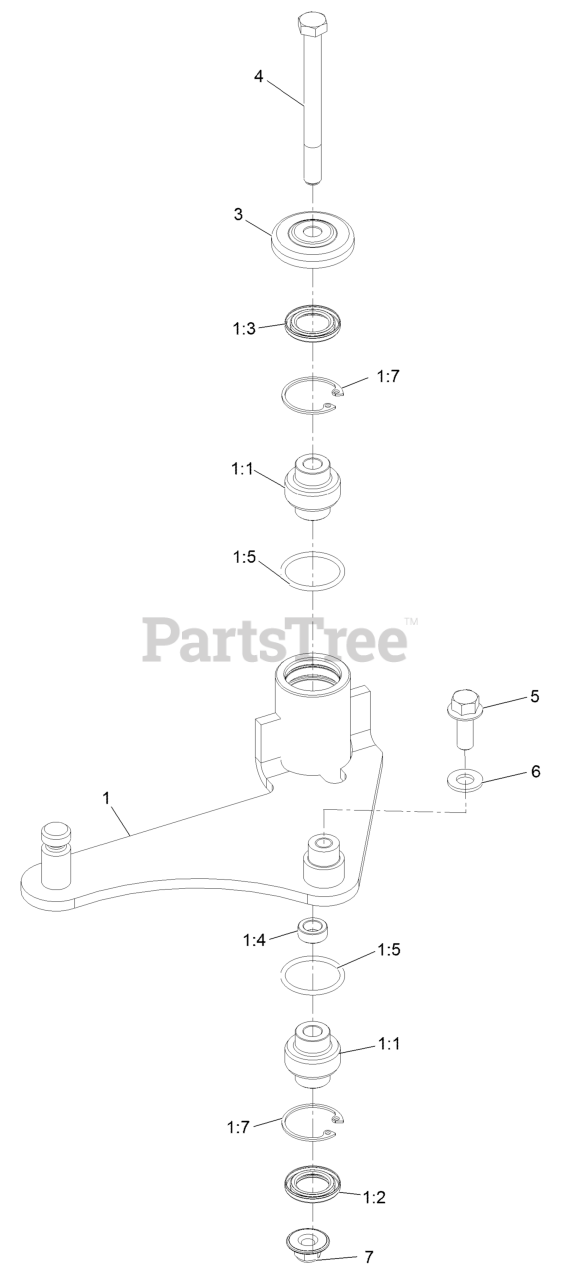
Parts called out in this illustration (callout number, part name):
1	ASM,Deck Idler
1:1	BEARING-SPHERICAL
1:2	SEAL-LIP, DOUBLE
1:3	SEAL-LIP, SINGLE
1:7	RING-SNAP
3	GUARD-TOP
4	SCREW-HH
5	SCREW-HHF
6	WASHER-FLAT
7	Nut-Nyloc 3/8-16 Flg
